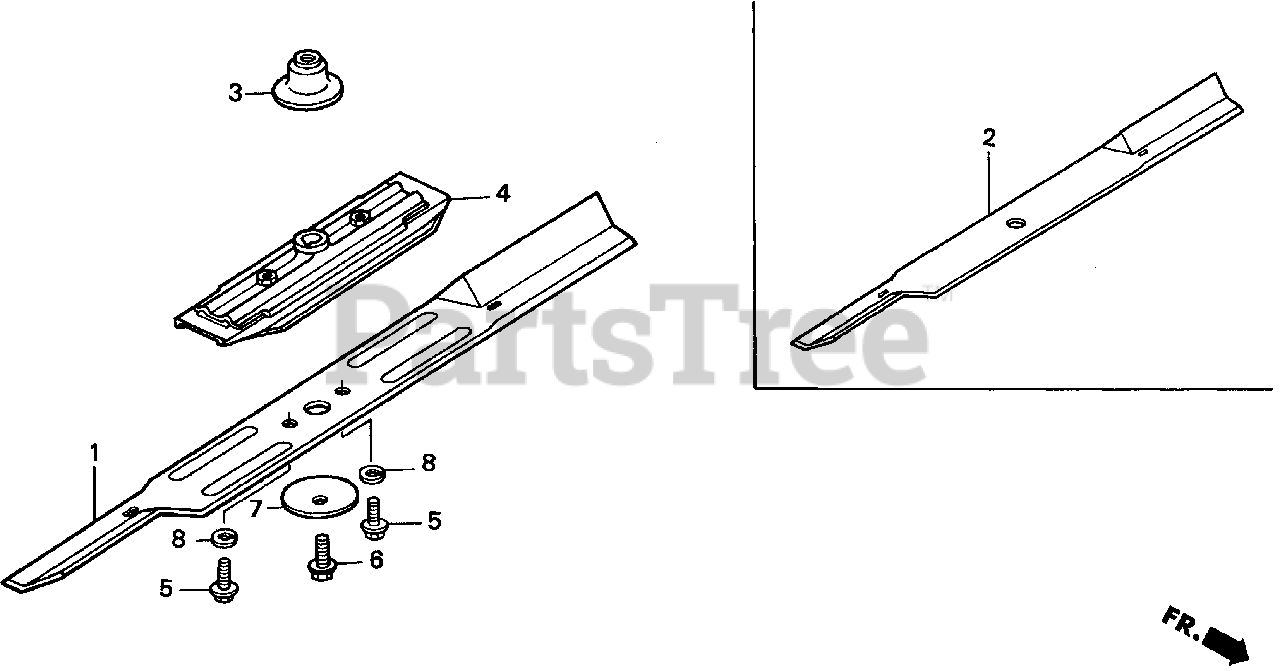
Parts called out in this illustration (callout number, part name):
1	BLADE, ROTARY
2	BLADE, ROTARY
3	HOLDER, BLADE (A)
4	HOLDER, BLADE (B)
5	BOLT, FLANGE (12X25)
6	BOLT, BLADE HOLDER (10X28)
7	WASHER, BLADE
8	WASHER, SPRING (12MM)
